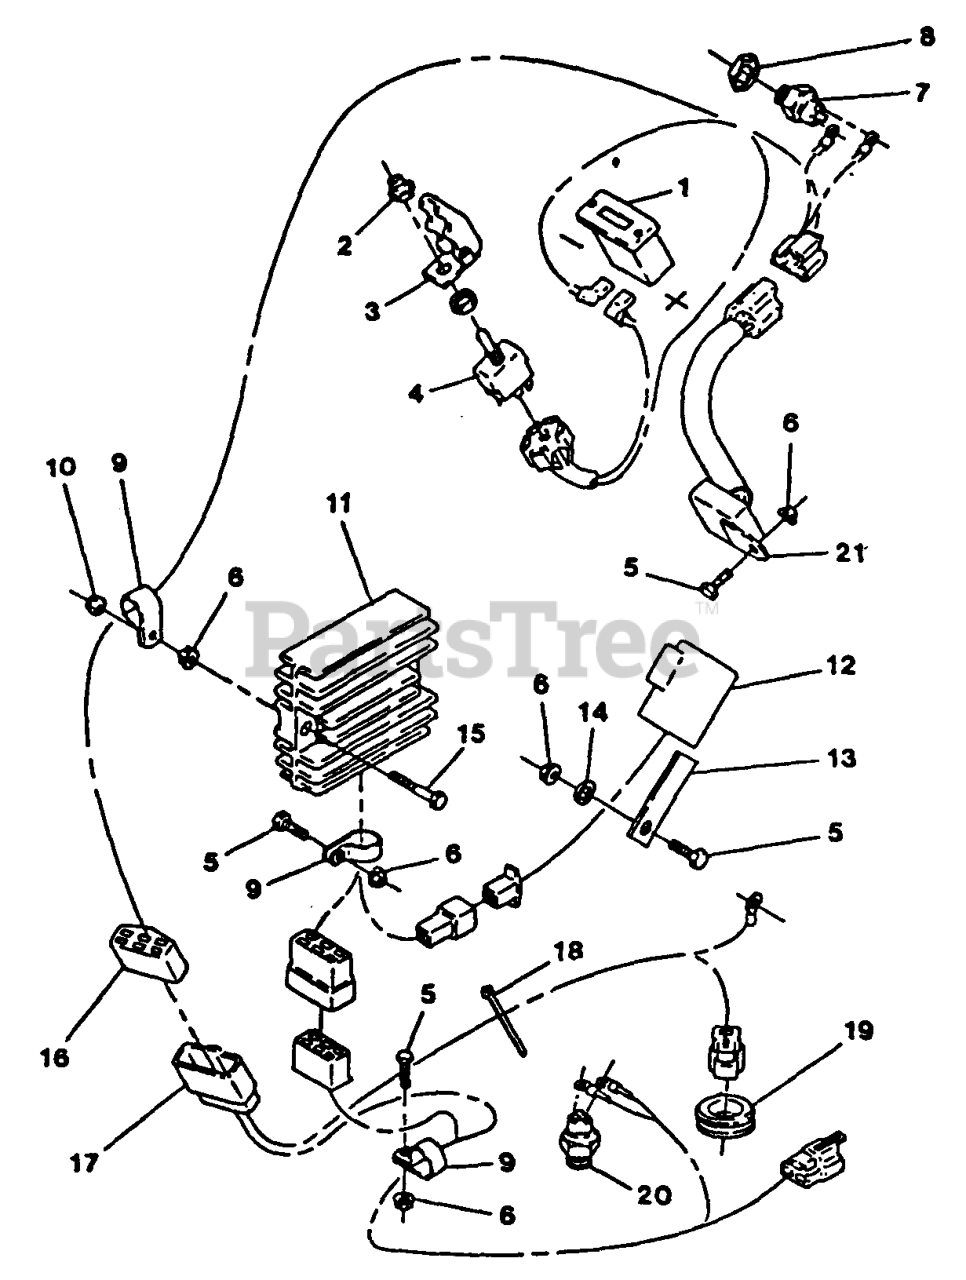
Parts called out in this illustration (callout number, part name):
1	METER-HOUR
2	BOOT-SWITCH, TOGGLE
7	SWITCH,OPERATOR CNTRL
9	CLIP-LOOM
18	TIE-CABLE
19	GROMMET
20	SWITCH-START, NEUTRAL
